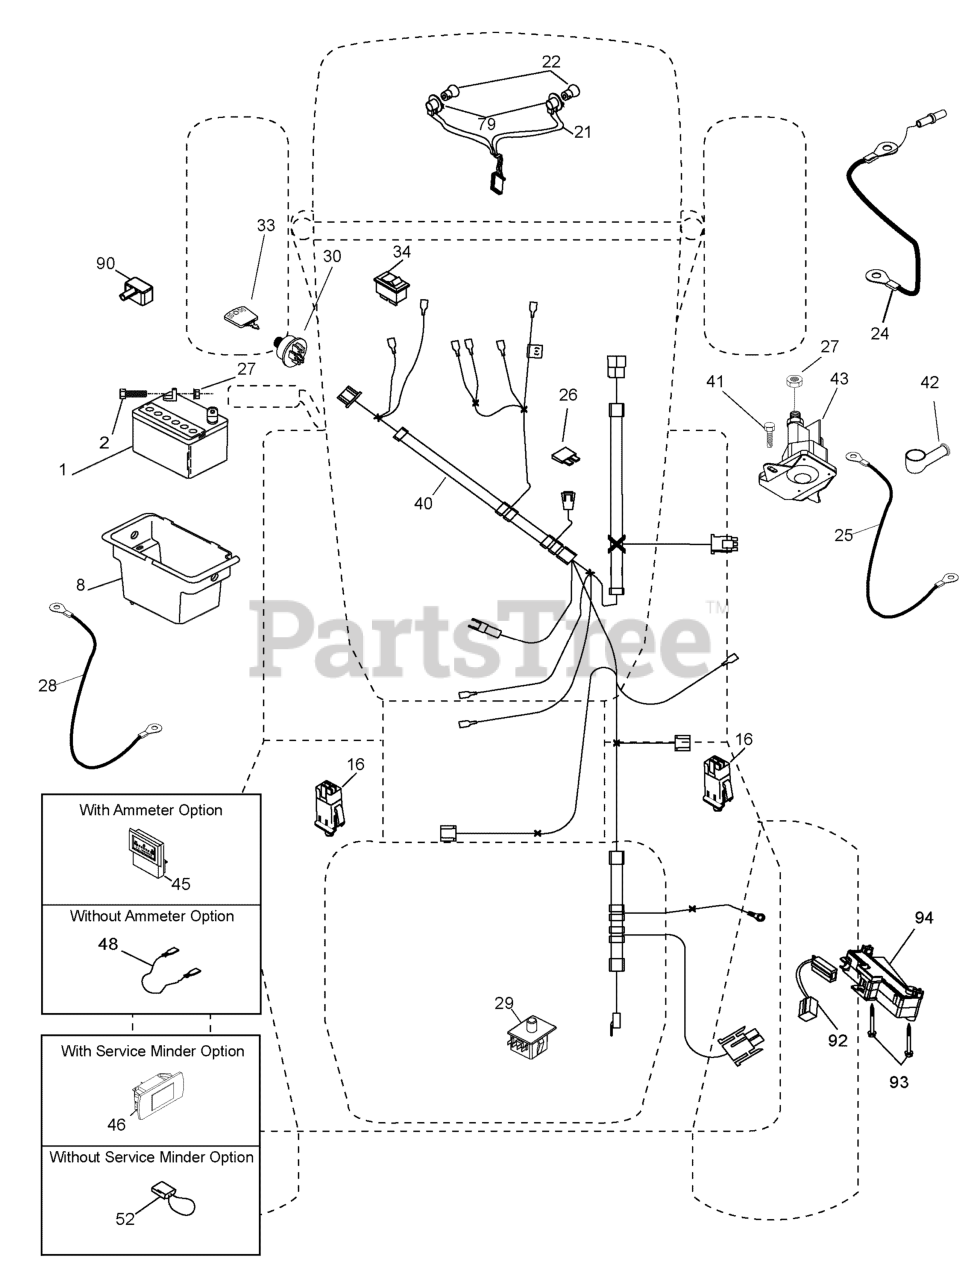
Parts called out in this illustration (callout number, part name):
1	BATTERY
2	BOLT, Hex Head ,1/4-20 UNC x 3/4
8	BOX, Battery
16	SWITCH, Interlock
21	HARNESS ASSEMBLY, Light (w/4152j
22	BULB, Light #1156
24	CABLE, Battery 6 Ga. 11" Red
25	CABLE, Battery
26	FUSE, 20 Amp
27	NUT, Hex Keps, 1/4-20 UNC
28	CABLE, Ground Black, 6 Ga. 12"
29	SWITCH
30	SWITCH, Ignition
33	KEY/CHAIN
34	SWITCH, Light/Reset
40	HARNESS, Ignition
41	BOLT, Hex Black, 1/4-20
42	COVER, Terminal Red
43	SOLENOID
79	SOCKET ASSEMBLY, Bulb Twistlock
90	COVER, Terminal Battery
92	HARNESS, Pigtail
93	SCREW, Plastite, 10-14 x 2.0
94	MODULE, Reverse
